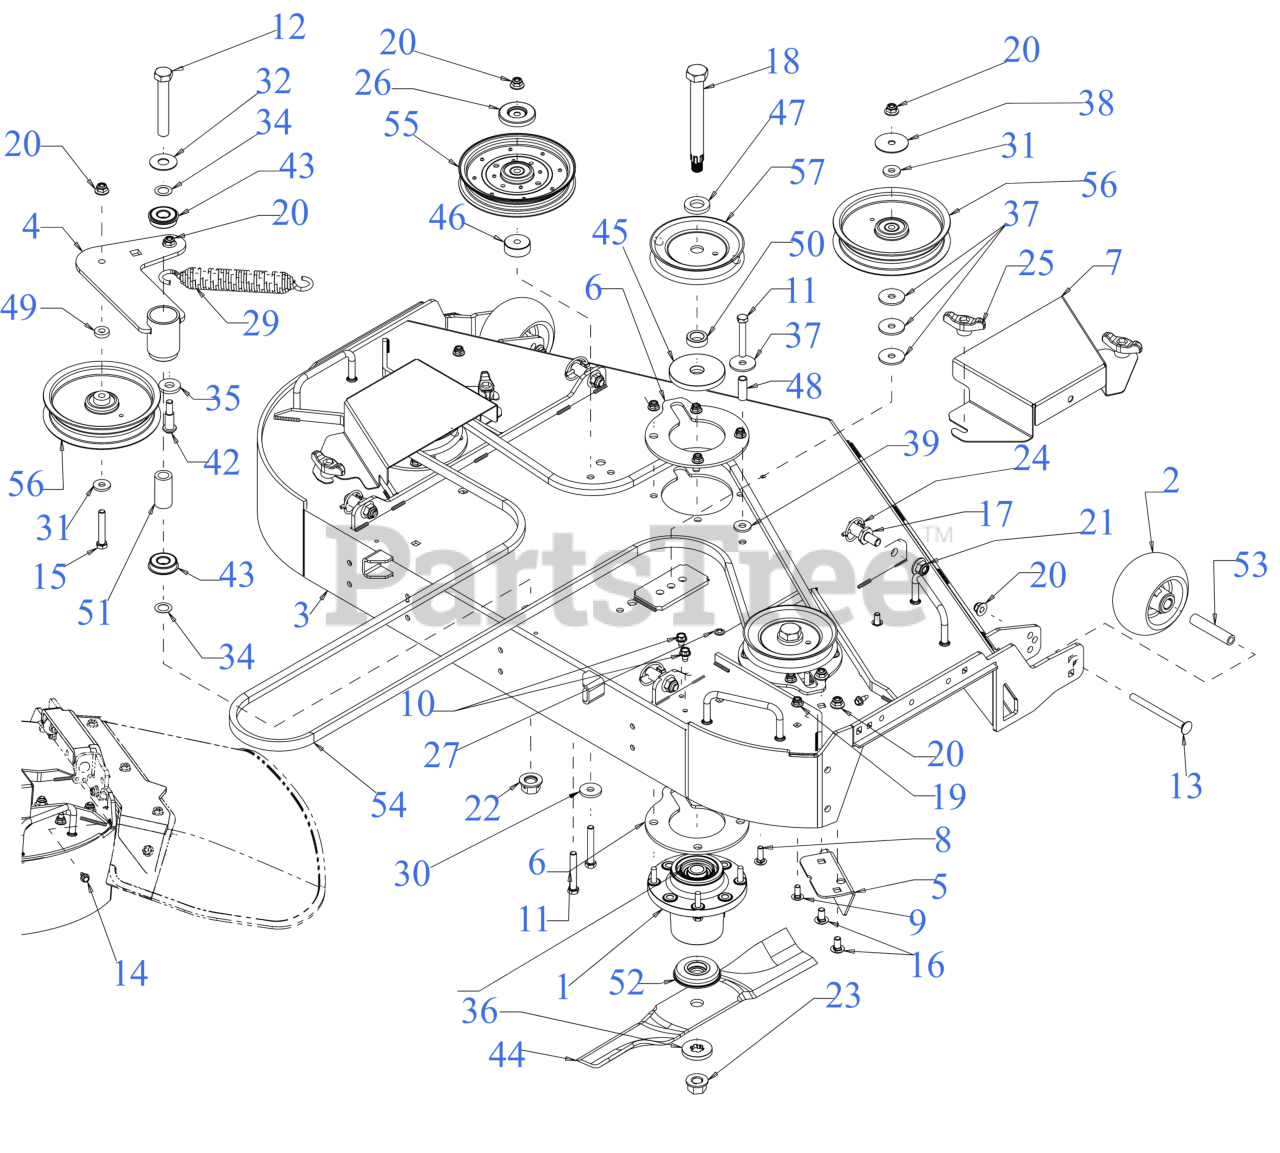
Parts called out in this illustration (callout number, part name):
1	SPINDLE ASSEMBLY
2	5" DIA DECK WHEEL COMPLETE
2	FLANGE BEARING
3	48" FAB DECK ASSEMBLY
4	IDLER ARM ASSEMBLY
8	CARRIAGE BOLT 5/16-18 x 1.00
9	CARRIAGE BOLT 5/16-18 x .75
10	SCREW 5/16-18 x .500
11	HEX SCREW-3/8-16X2.5 GR5
12	SCREW 5/8-18 x 4 GR5
13	CARRIAGE BOLT 3/8-16 x 4.25 GR5
14	SCREW 1/4-20X.625
15	SCREW 3/8-16 x 2.25 GR5
16	CARRIAGE BOLT 3/8-16 x .75
18	SPINDLE SHAFT
19	FLANGE LOCK NUT 5/16-18
23	FLANGE NUT - 5/8-18 GDE 8
24	LYNCH PIN .1875
25	WING KNOB 5/16-18
26	PULLEY CAP
28	DECK SKID PLATE (LH)
29	SPRING 1.25" DIA x 8.5" LONG
30	FLAT WASHER
31	FLAT WASHER .385 x 1.00 x .135
32	FLAT WASHER-.63IDX1.595ODX.62
33	FLAT WASHER
34	FLAT WASHER
35	FLAT WASHER
35	FLAT WASHER .531 x 1.25 x .181
36	FLAT WASHER - SPECIAL
37	FLAT WASHER .406X1.500X.105
38	HUB CAP WASHER .406 x 1.92 x .060
39	FLAT WASHER .406ID X1.0 OD
41	SHOULDER SCREW .43X.29X5/16-18 TT
42	SHOULDER SCREW .50X.925
43	BALL BEARING W/RET
44	17" BLADE (HI LIFT)
44	Cub Cadet 48" HI LIFT BLADE SET
44	17" HI-LIFT BLADE 0.756 ID
44	LOW-LIFT 17" BLADE (48"DECK)
44	BLADE-HI LIFT 17.0
44	17" BLADE (MULCH)
45	DECK SPINDLE SPACER
46	SPACER - .385 ID x 1.500DX .585 L
47	SPACER .812 ID x .218 LG
50	SPACER (.792 x 1.20 x .380)
51	SPACER 0.63 x 1.00 x 2.01
52	SPACER 0.790 x 2.75 x 0.486
53	WHEEL SPACER .38ID x 3.04LG
54	DECK BELT - B SEC x 143.25
55	IDLER PULLEY
56	IDLER PULLEY (6.00" DIA)
57	DECK SPINDLE PULLEY (5.39 DIA)
